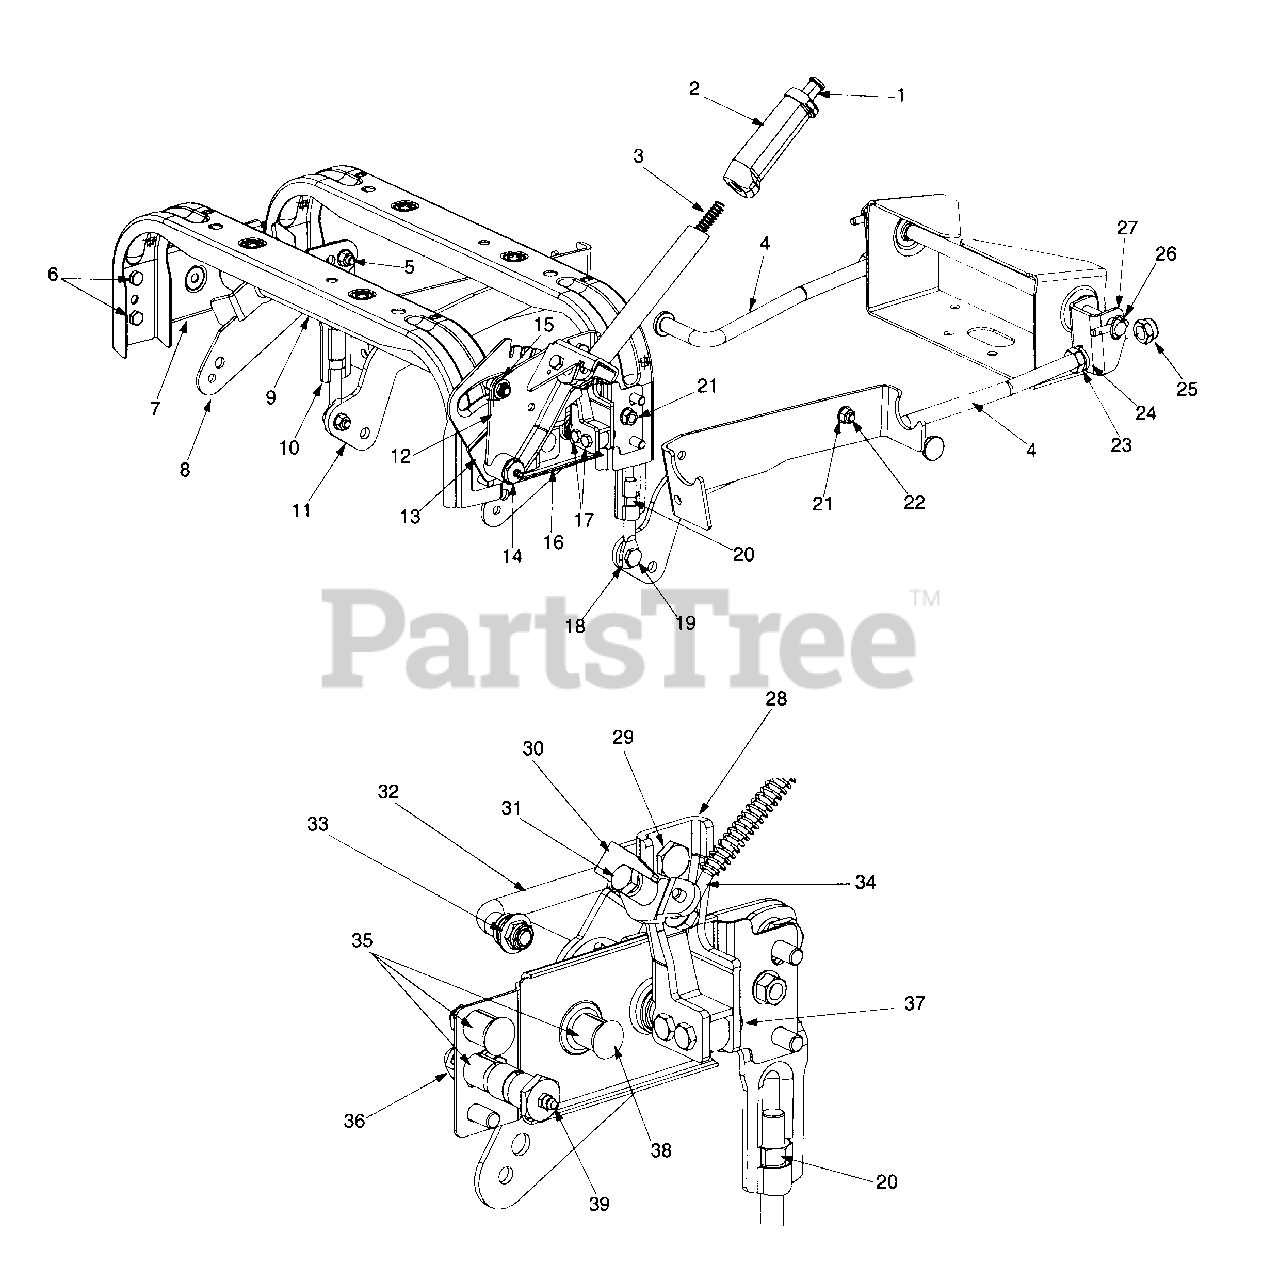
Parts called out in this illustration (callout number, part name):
1	Handle Button
2	Handle Deck Lift Grip
3	Compression Spring
4	Front Lift Rod
5	Shoulder Screw .500 Dia x .434
6	Hex Cap Screw 3/8-16 x .75
7	Shaft Mounting Bracket - LH
15	Top Lock Jam Nut 3/8-16
16	Shaft Mounting Bracket - RH
17	Hex Cap Screw 5/16-18 x 1.375
18	Eye Bolt Adjustable Link
19	Shoulder Screw 3/8-16
20	Hex Nut 1/2-13
21	Flange Lock Nut 3/8-16
22	Shoulder Screw 3/8-16 .56 x .27
23	Jam Nut 5/8-11
24	Lock Washer 5/8
25	Lock Hex Nut 5/8-11
26	Clevis Pin
31	Hex Cap Screw 3/8-16 x 2.25
32	Lift Link Rod
33	Flat Washer .406 x .875
34	Handle Arm
35	Spacer .448 ID x .688 OD
36	Lock Nut 7/16-14
37	Hex Center L-Nut 5/16-18
38	Hex Screw 3/8-16 x 1.50
39	Grease Fitting
